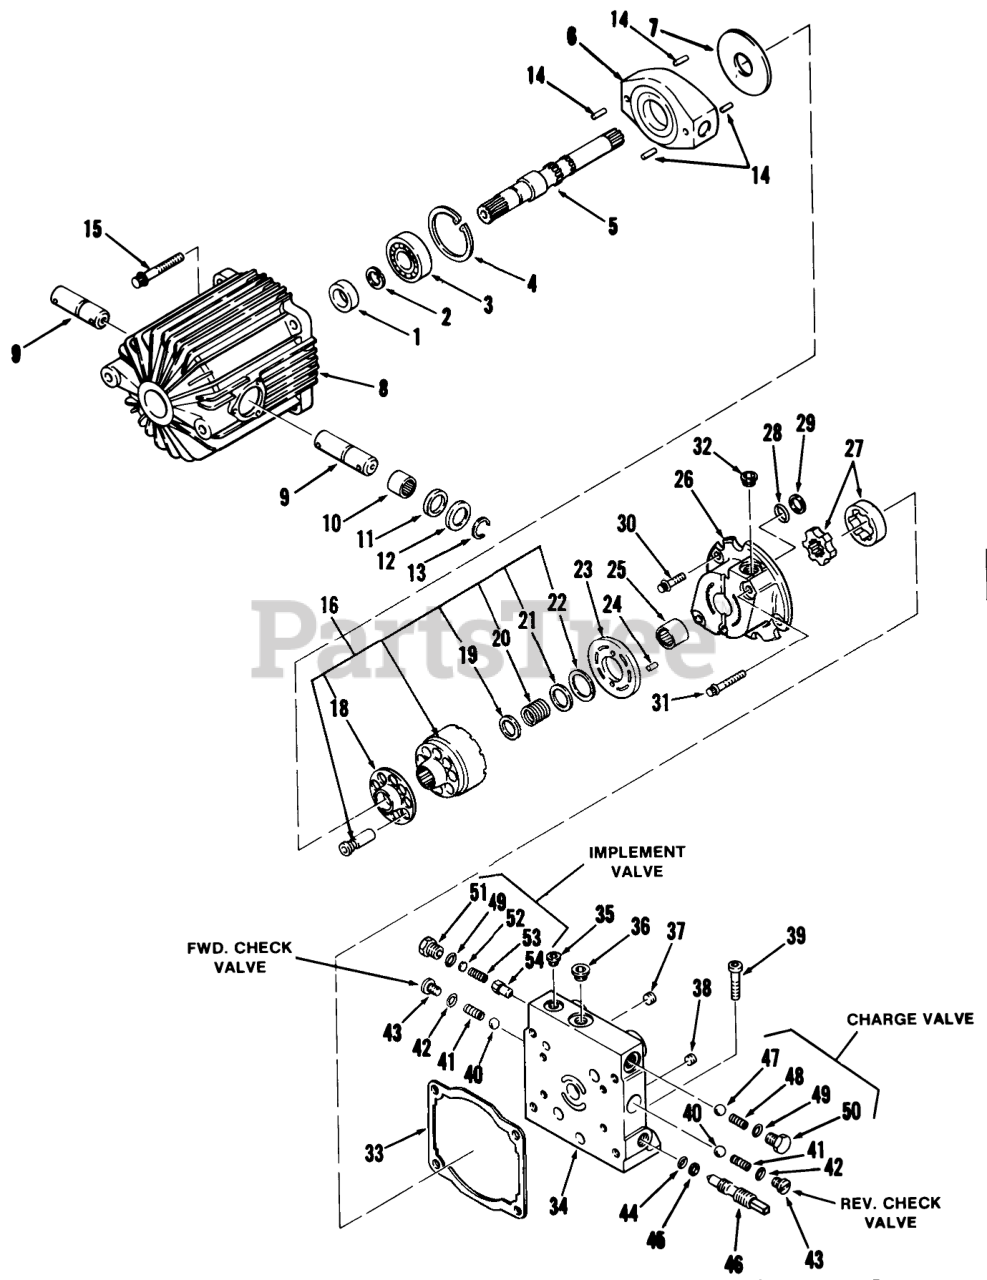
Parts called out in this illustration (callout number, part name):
1	SEAL
2	Snap Ring
3	Ball Bearing
5	Pump Shaft
6	Variable Swash Plate
7	Thrust Plate
8	Pump Housing
9	Trunnion Shaft
10	Needle Bearing
11	SEAL
12	WASHER-LAMBERT
13	RING-LAMBERT
14	Spirol Pin
15	Cap Screw
16	Cylinder Block Kit Inc 18-22
18	RETAINER-SUN 3100194
19	Spacer
20	Spring
21	Front Washer
22	RING-SUN9006250-0112
23	PLATE-VALVE
24	Locating Pin
25	Needle Bearing
26	Charge Pump Housing
27	Assy-Gerotor
28	O RING
29	RING BACKUP
30	Cap Screw Short
31	Cap Screw Long
32	Socket Head Plug
33	Gasket-Pump
34	End Cap-Pump
35	Socket Head Plug
36	Socket Head Plug
37	Pipe Plug
38	Pipe Plug
39	Cap Screw
40	Ball
41	Spring
42	O RING
43	PLUG
44	O-RING
45	Back Up Ring
46	VALVE
47	Ball
48	Spring Chg. Rel. Valve
49	O RING
50	Plug
52	Shim Set
53	Spring-Implement Valve
54	Cone
